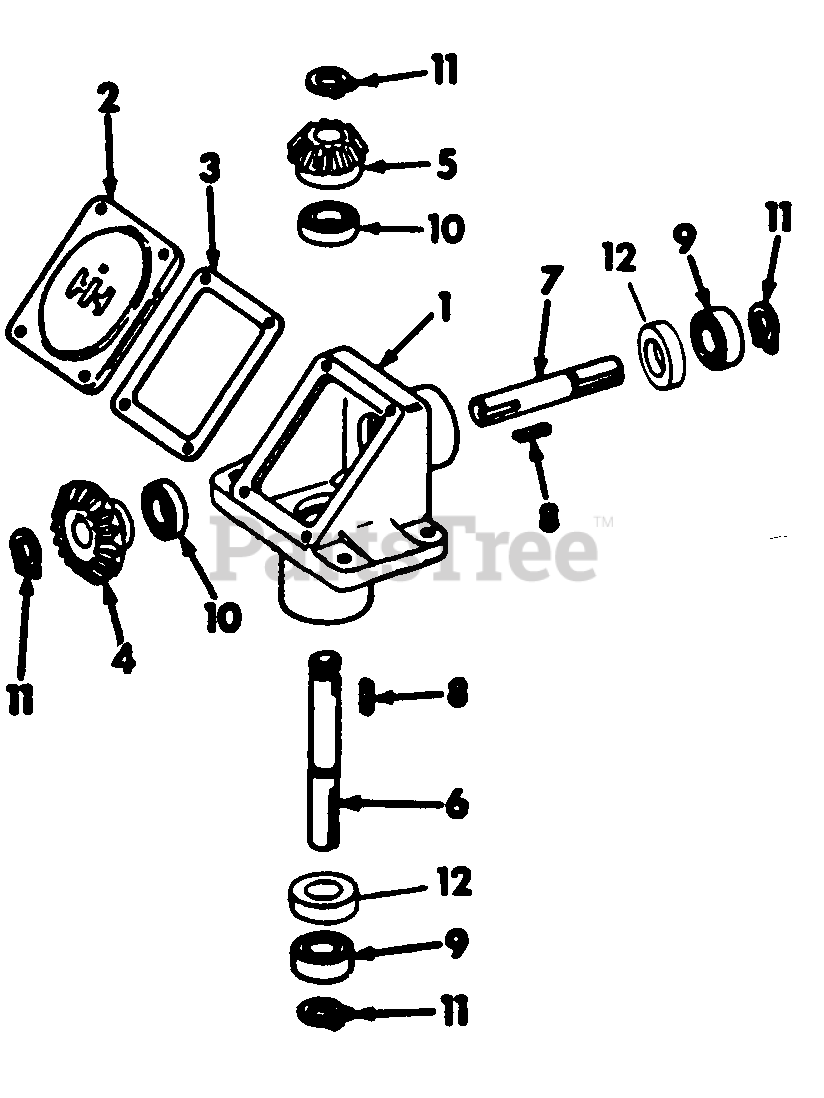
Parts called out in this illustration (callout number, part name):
2	Cover, Gear Box
3	Gasket, Gear Box Cover
4	Gear, Bevel
5	Gear, Bevel Pinion
6	Shaft, Input
7	Shaft, Output
8	Key, 3/16 X 11/16 Sq Parallel
9	Bearing, Ball
10	Bearing, Ball
11	Ring, Retaining Snap
